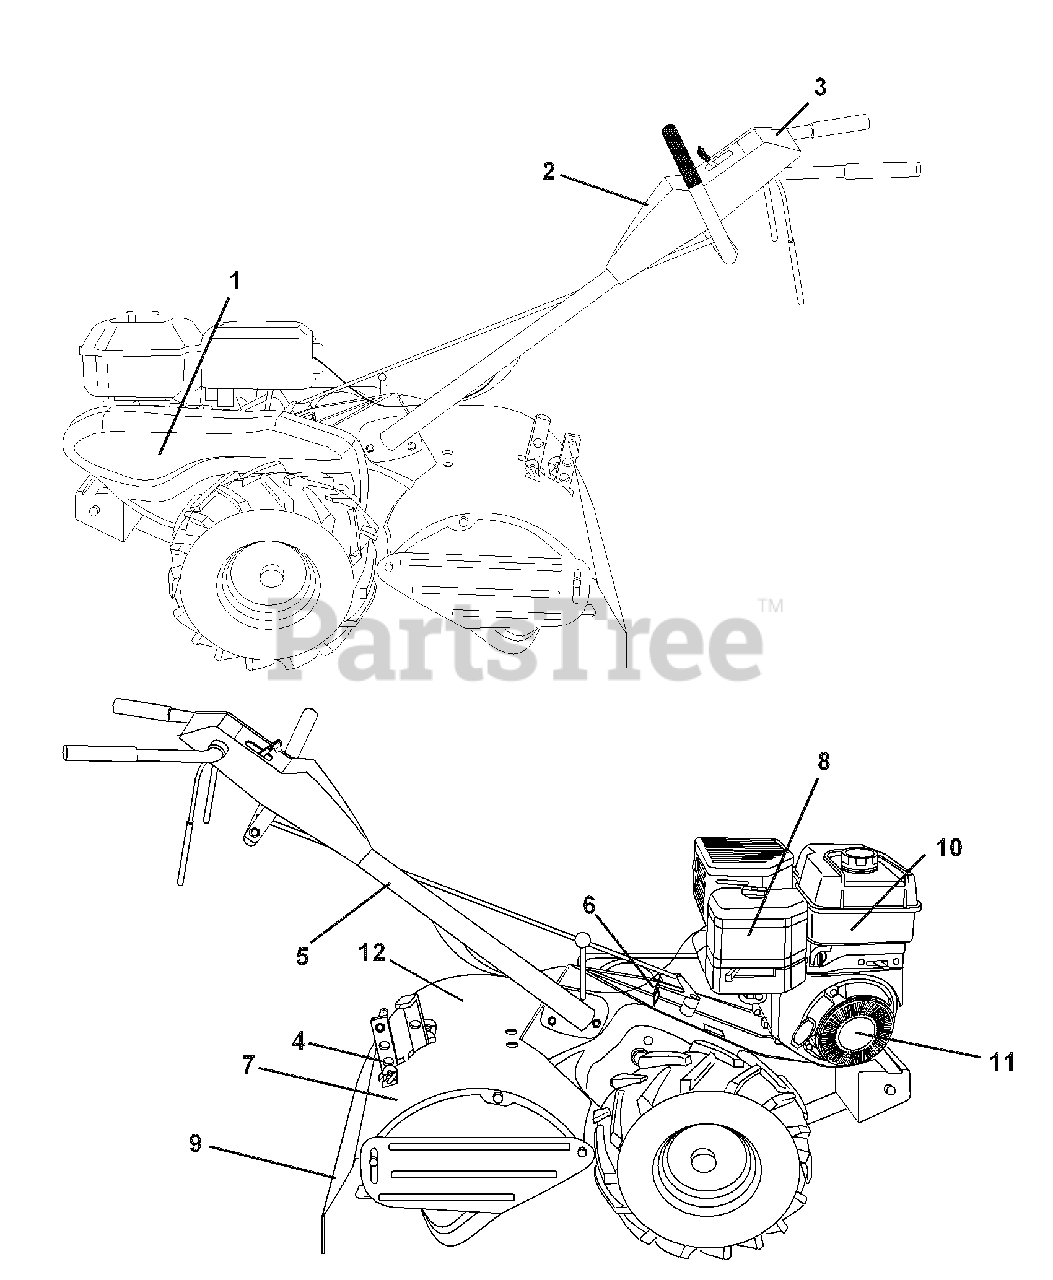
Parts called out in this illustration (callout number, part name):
1	Decal, Belt Guard
2	Decal, Console
3	Decal, Console
4	Decal, Tine Shield
5	Decal, Hand Placement
6	Decal, Shift Indicator
7	Decal, Reverse
8	Decal, Engine B&S
9	Decal, Warning, Rotating Tines
10	Decal, Engine Intek REF
11	Decal, Rewind Intek
12	Decal, Forward
12	Manual, Owner’s
